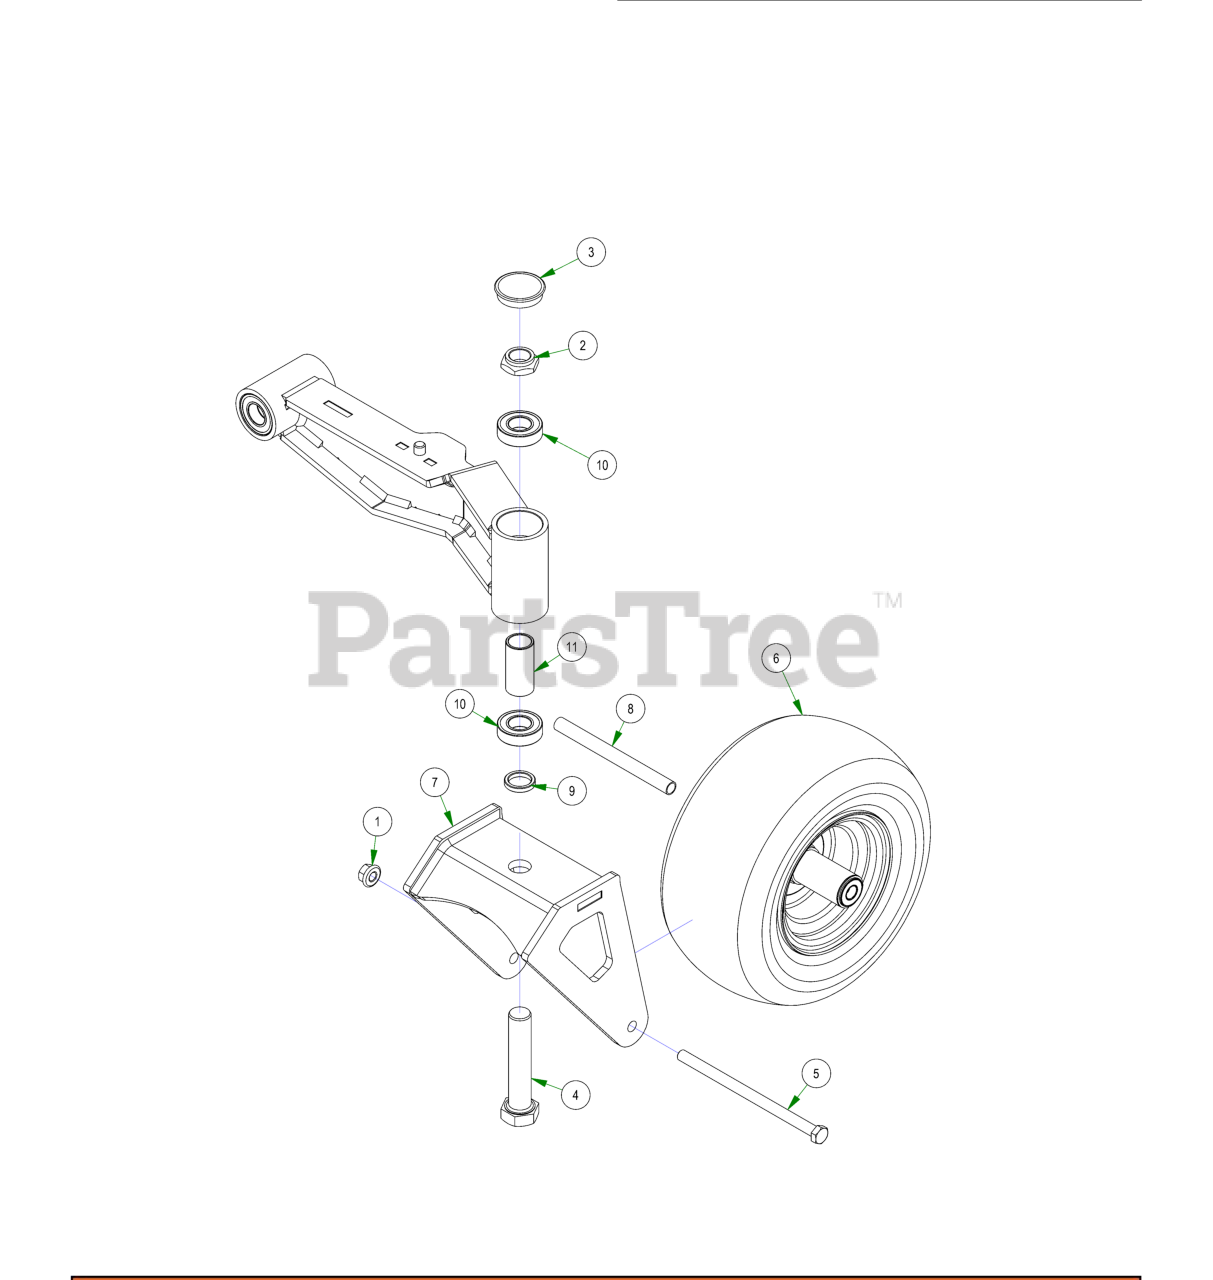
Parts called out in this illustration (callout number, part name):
1	1/2-13 NYLON INSERT FLANGE LOCKNUT ZINC
2	1"-14 NYLON INSERT JAM LOCKNUT ZINC
3	2017 Bearing Cover
4	1"-14 X 5 HEX CAP SCREW (GR.8) ZINC YELLOW
5	1/2-13 X 8-1/2 HEX CAP SCREW (GR.5) ZINC
6	13x6.5-6 Black Tire and Wheel Assembly
7	2019 Stand-on Front Fork Weldment
8	Front Wheel Spanner
9	Spacer, 1x1.375x.25
10	1641 BEARING W/2 CONTACT RUBBER SEALS
11	2016 Front Bearing Spacer
